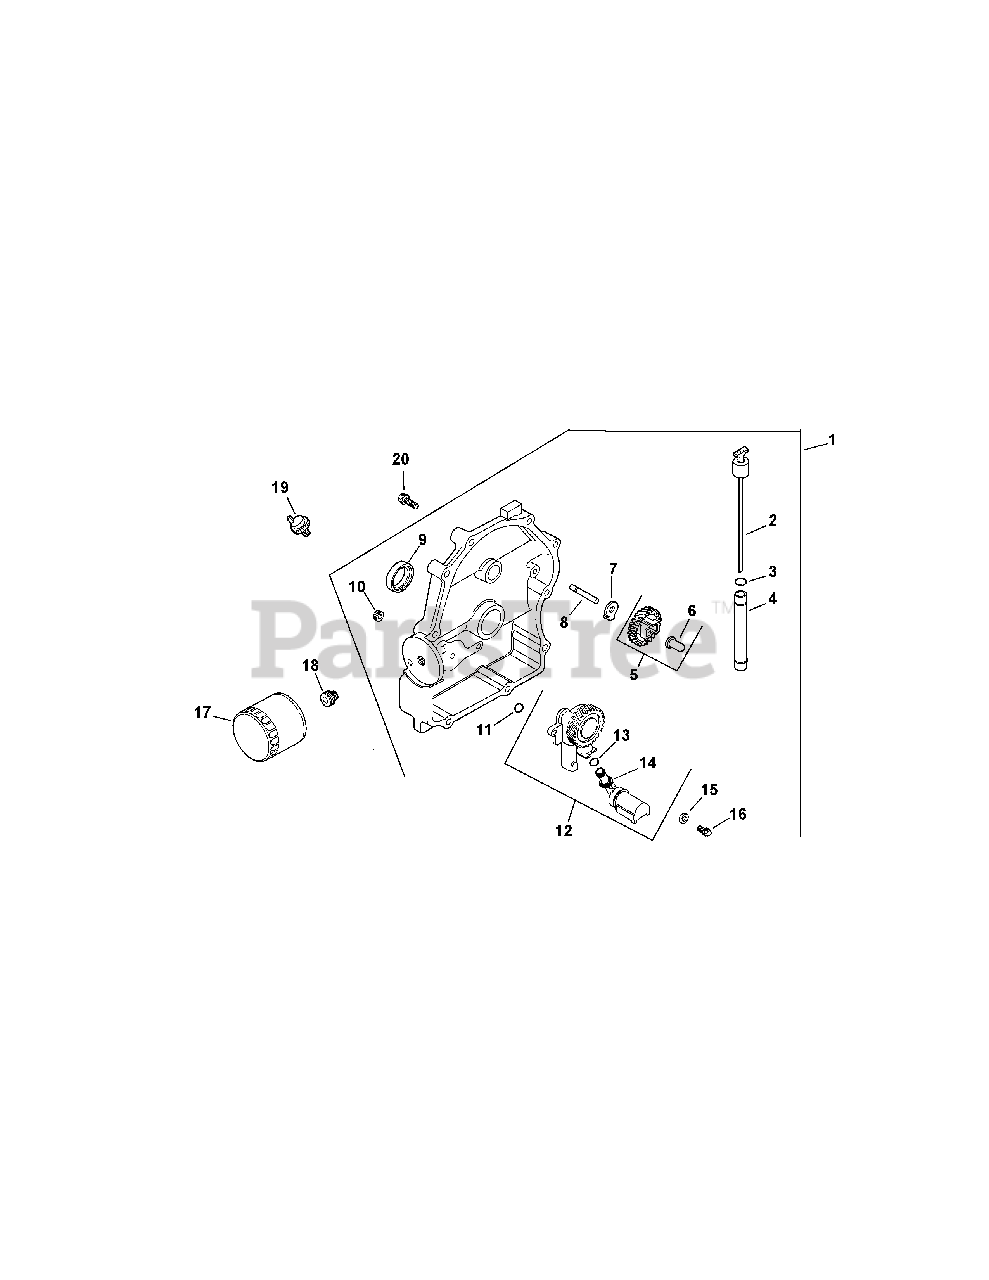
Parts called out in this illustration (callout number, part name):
1	KIT, CLOSURE PLATE ASSEMBLY
4	KIT, OIL FILL TUBE - METAL
5	KIT, GOVERNOR GEAR W/PIN
6	PIN, GOVERNOR REGULATING
8	SHAFT, GOVERNOR GEAR
10	PLUG, CTSK PIPE 1/8''
12	KIT, OIL PUMP ASSEMBLY
13	O-RING, OIL PICK-UP
14	PICK-UP, OIL
15	WASHER, FLAT 6 MM
16	SCREW, FLG THD FRM M6X1.0X25
18	NIPPLE, OIL FILTER
19	SWITCH, OIL PRESSURE
20	SCREW, FLG M8X1.25X45
